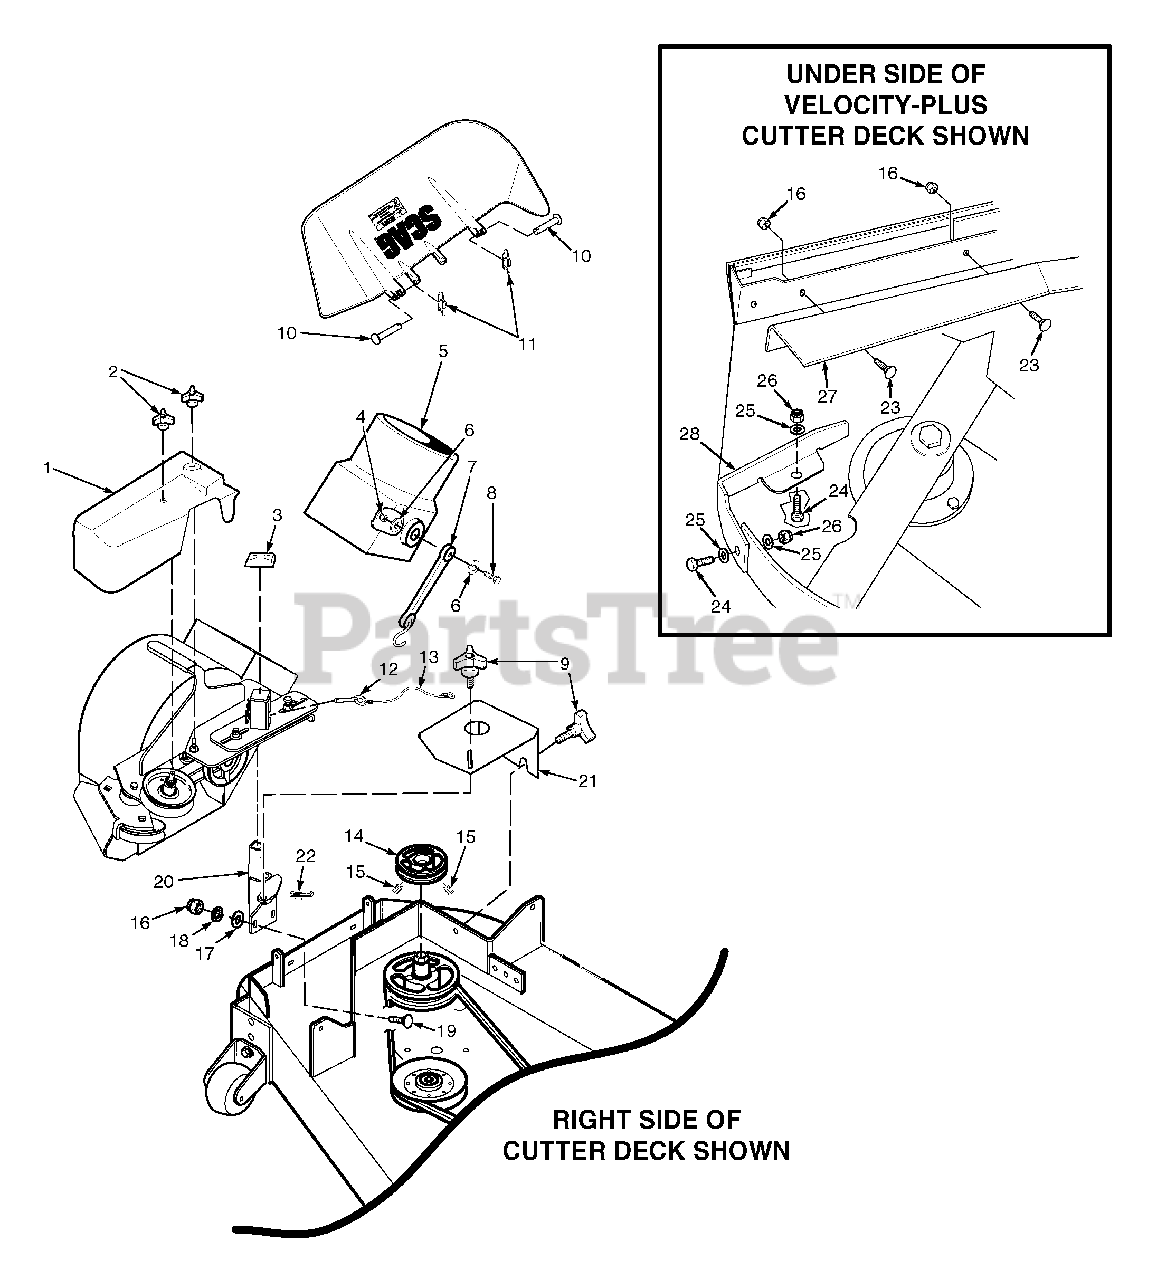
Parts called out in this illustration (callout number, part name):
1	Belt Cover, GC-STT - 52"
2	Wingnut, Plastic 3/8" Small
3	Cap, Square Vinyl
4	Nut, Elastic Stop 1/4-20
5	Adapter, Blower GC-STT,
6	Flatwasher, 1/4-.312 x .750 x .065
7	Rubber Strap 7-3/4"
8	Bolt, Hex Head 1/4-20 x 1-1/4"
9	Knob W/Stud, 3/8-16 x 1-1/4"
10	Clevis Pin, 5/16 x 1-1/2"
11	Pin, Rue Cotter 5/16 Dia.
12	Pin, Ring 1/2 x 2-1/4"
13	Lanyard
14	Pulley, 4-1/2" for 52" Deck
15	Setscrew, 5/16-18 x 3/8"
16	Nut, Elastic Stop 3/8-16
17	Lockwasher, 3/8"
18	Flatwasher, 3/8-.391 x .938 x .105
19	Bolt, Carr. 3/8-16 x 1-1/4" Grade 5
20	Mounting Post Weldment, Blower - 52"
21	Belt Cover, GC-STT-52V
23	Bolt, Carriage 3/8-16 x 1"
24	Bolt, Hex Head 5/16-18 x 1"
25	Flatwasher, 5/16-.375 x .875 x .083
26	Nut, Elastic Stop 5/16-18
27	Baffle, Front 52" Deck
28	Baffle, Turbo 52" Deck
